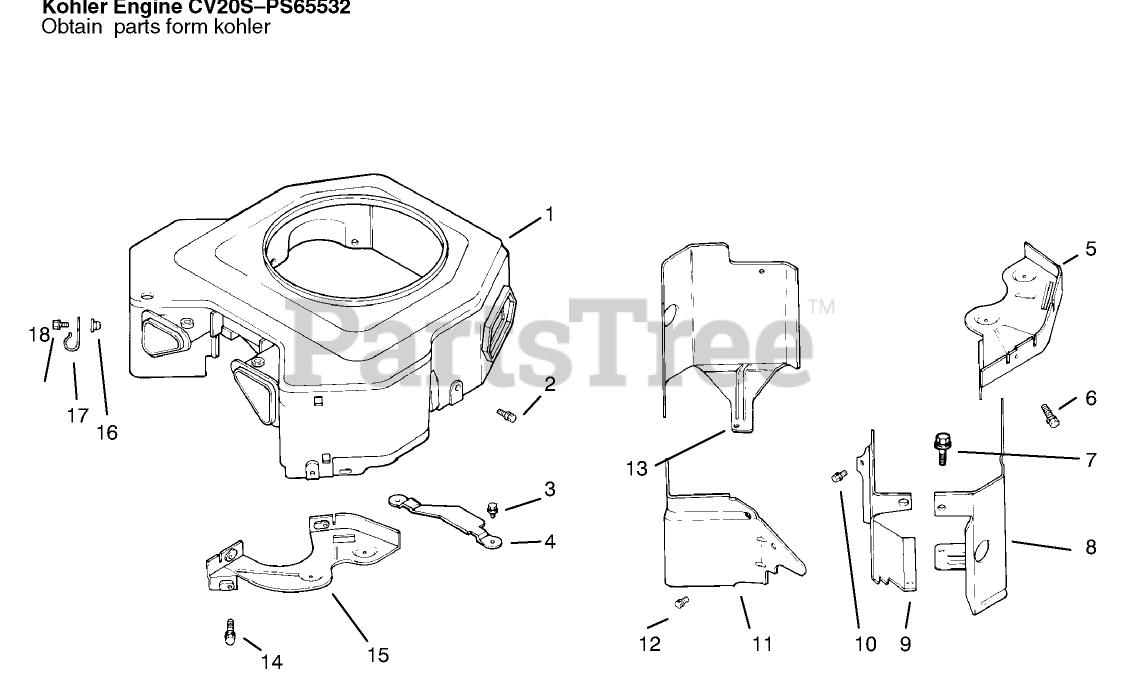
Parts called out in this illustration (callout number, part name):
1	Housing-Blower ASM (Only C)n: 72103, 72083)
4	Guard-Flywheel (Only On: 72103, 72083)
5	Plate-Backing #2 side
8	Baffle Cylinder #2 Side
9	Baffle-Valley #1 Side (Only On: 72103)
11	Baffle-Valley #2 Side (Only On: 72103, 72083)
13	Baffle-Cylinder #1 Side (Only On: 72103)
15	Plate-Backing #1 Side (Only On: 72103, 72083)
17	Clip-Cable (Only On: 72103)
